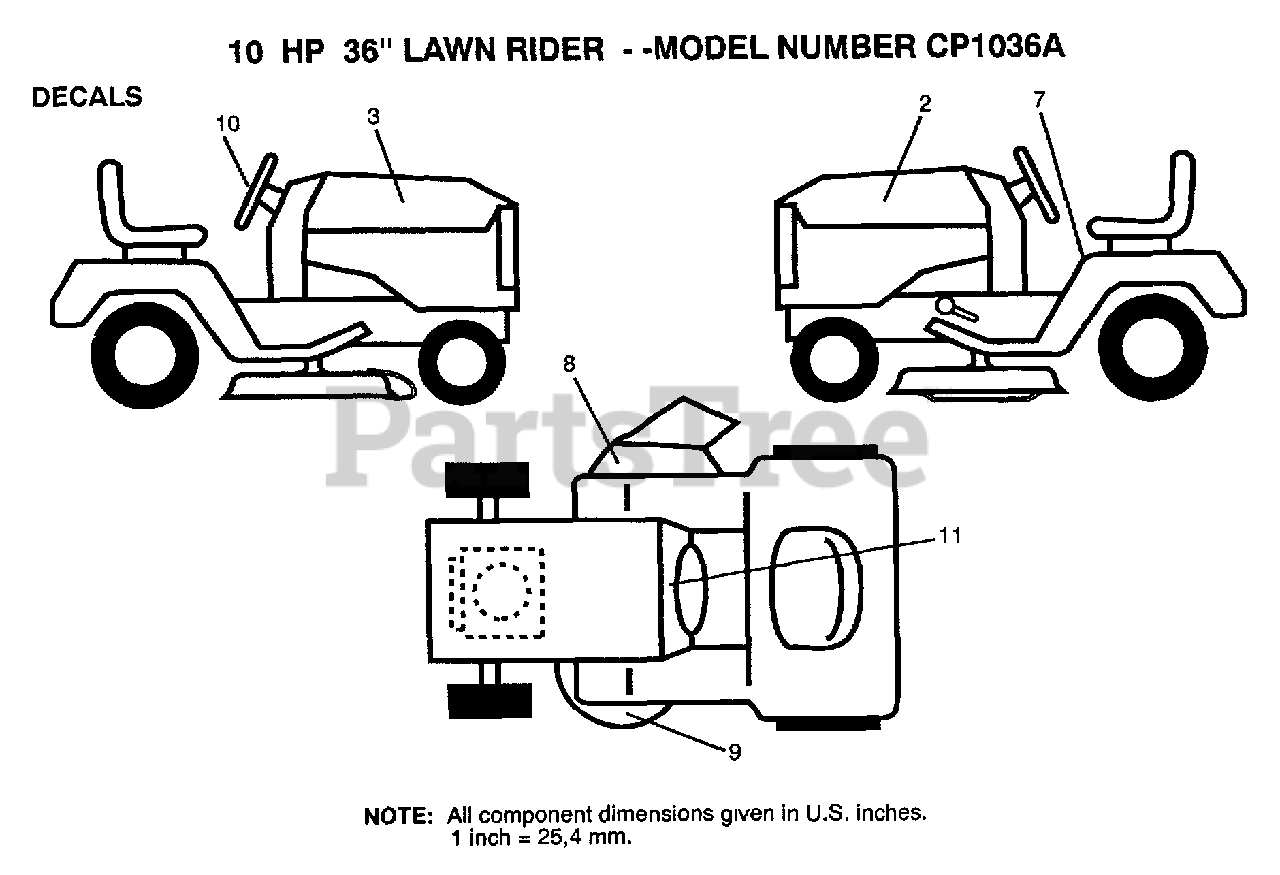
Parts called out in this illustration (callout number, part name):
7	DECAL
8	DECAL WARING
9	DECAL INSTRUCTION CAUTION
